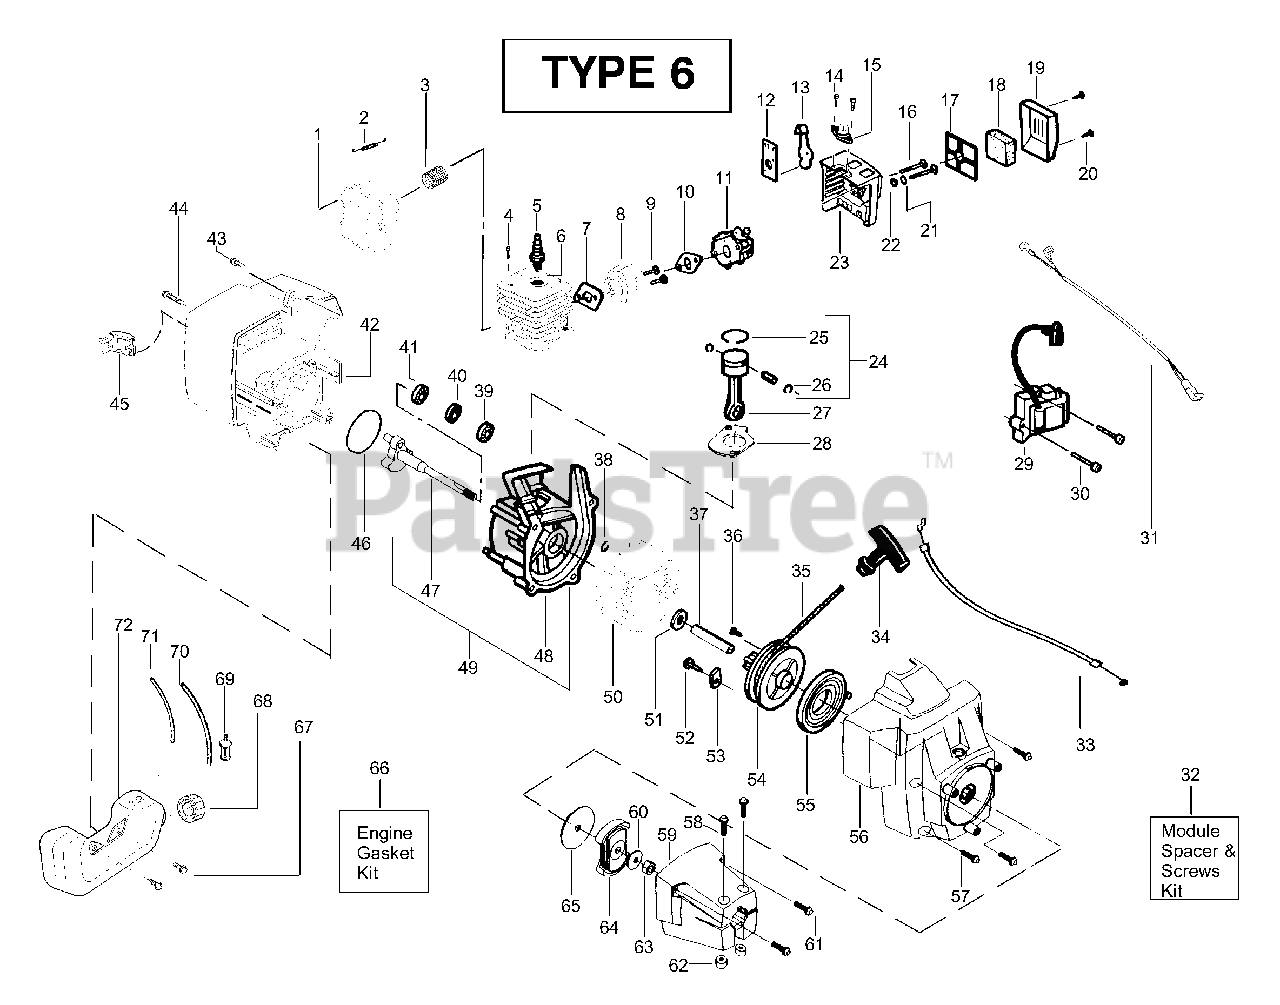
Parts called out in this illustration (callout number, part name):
1	Kit - Muffler
2	Spring-Muffler
3	Kit-Spark Arrestor
4	Screw-Cylinder
5	Spark Plug (RCJ-6Y)
6	Kit - Cylinder
7	Gasket-Cyl./Carb. (kit)
8	Adapter-Carb.
10	Gasket-Carb. (kit)
11	Kit-Carb. Assy. (WT-639)
12	Choke Plate Mounting
13	Shutter-Choke
14	Screw-Air Purge
15	Assy-Air Purge
17	Plate - Filter Support
18	Foam-Air Filter
19	Cover-Air Box
21	Spacer-Choke
23	Box-Air Filter
24	Kit - Piston
25	Piston Ring
26	Retainer-Piston Pin
27	Kit-Connecting Rod Assy.
28	Gasket-Cylinder (kit)
29	Ignition Module
31	Assy-Switch Wire
32	Kit-Module Spacer & Screws
33	Assy-Throttle Cable
34	Handle-Starter
35	Kit - Rope
37	Spacer-Flywheel
38	Retain. Ring-C'shaft
39	Outer Bearing
40	Kit-C'case Seal
41	Inner Bearing
42	Shroud-Rear
44	Screw
45	Guard-Muffler
46	O-Ring-C'case/Shrd (kit)
47	Assy-Crankshaft
48	Assy-Crankcase
49	Assy-C'case & C'shaft
50	Assy-Flywheel
53	Retainer
54	Kit-Starter Pull
55	Spring-Starter
56	Assy.-Fan Hsg
57	Screw
59	Assy-Clutch Hsg.
60	Washer-Flat
63	Nut-Clutch
64	Assy-Clutch
65	Washer-Clutch
66	Kit-Engine Gasket
67	Retainer-Tank
68	Assy-Fuel Cap
69	Assy-Fuel Pickup
70	Kit-Fuel Line
71	Kit-Fuel Line
72	Assy-Fuel Tank
